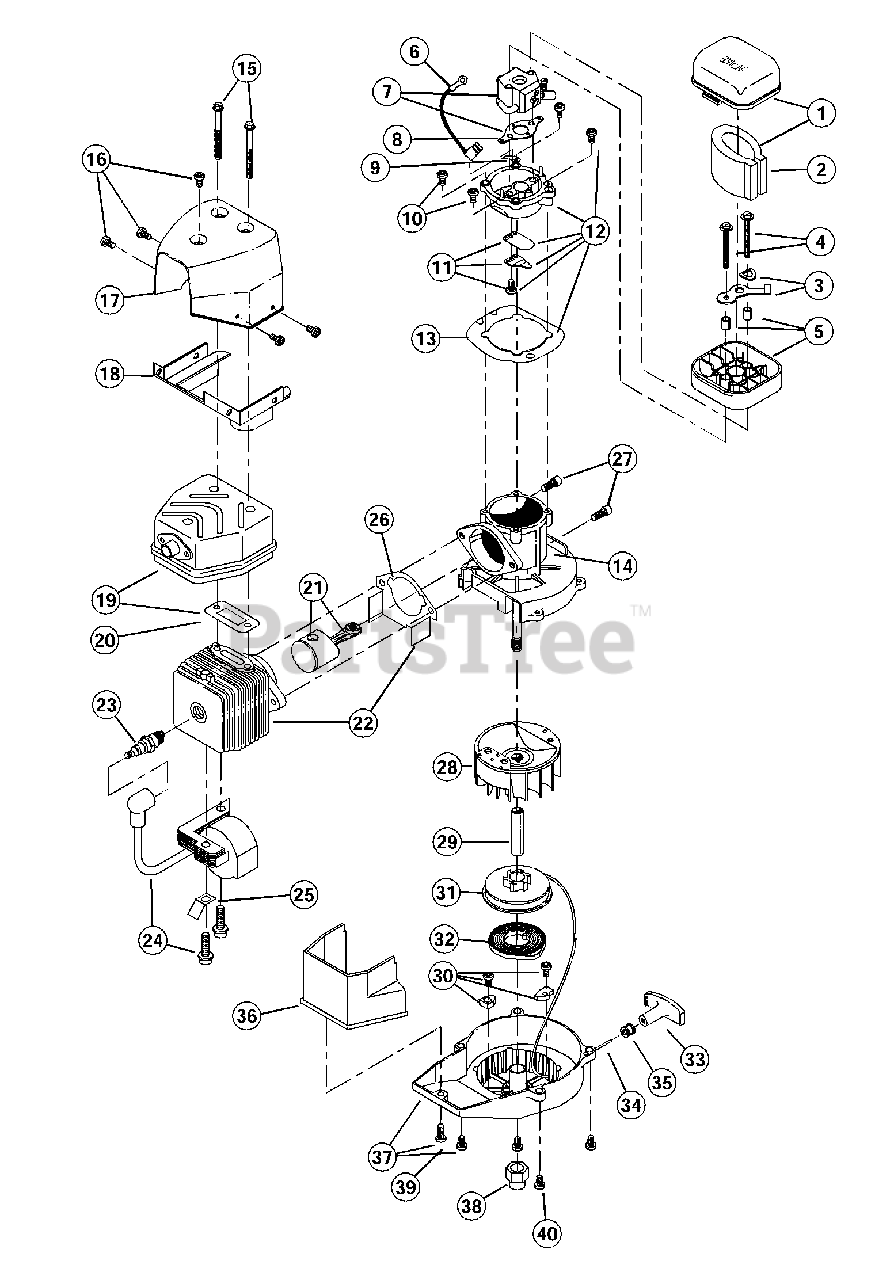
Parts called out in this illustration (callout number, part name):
1	Air Cleaner Cover Assembly
2	Air Cleaner Filter
3	Choke Lever Assembly
4	Mounting Bolts
5	Air Cleaner Base
6	Wire Lead
7	Carburetor Assembly
8	Carburetor Gasket
9	Ground Tab
10	Reed Plate Mounting Screw
11	Complete Reed Plate Assembly
12	Reed Assembly
13	Reed Plate Gasket
14	Crankcase Service Assembly
15	Muffler Mounting Bolt
16	Mounting Screw Assembly
17	Upper Heat Shield
18	Lower Heat Shield
19	Muffler Assembly
20	Exhaust Gasket
21	Piston and Rod Assembly
22	Cylinder Assembly
23	Spark Plug
24	Module Assembly
25	Ground Tab
26	Cylinder Gasket
27	Cylinder Bolt
28	Flywheel Assembly
30	Pulley Retainer Assembly
31	Recoil Pulley Assembly
32	Recoil Spring
33	Pull Handle
35	Rope Guide
36	Shroud Extension
37	Starter Housing Assembly
38	Drive Nut
39	Shroud Extension Screw
40	Housing Screw
